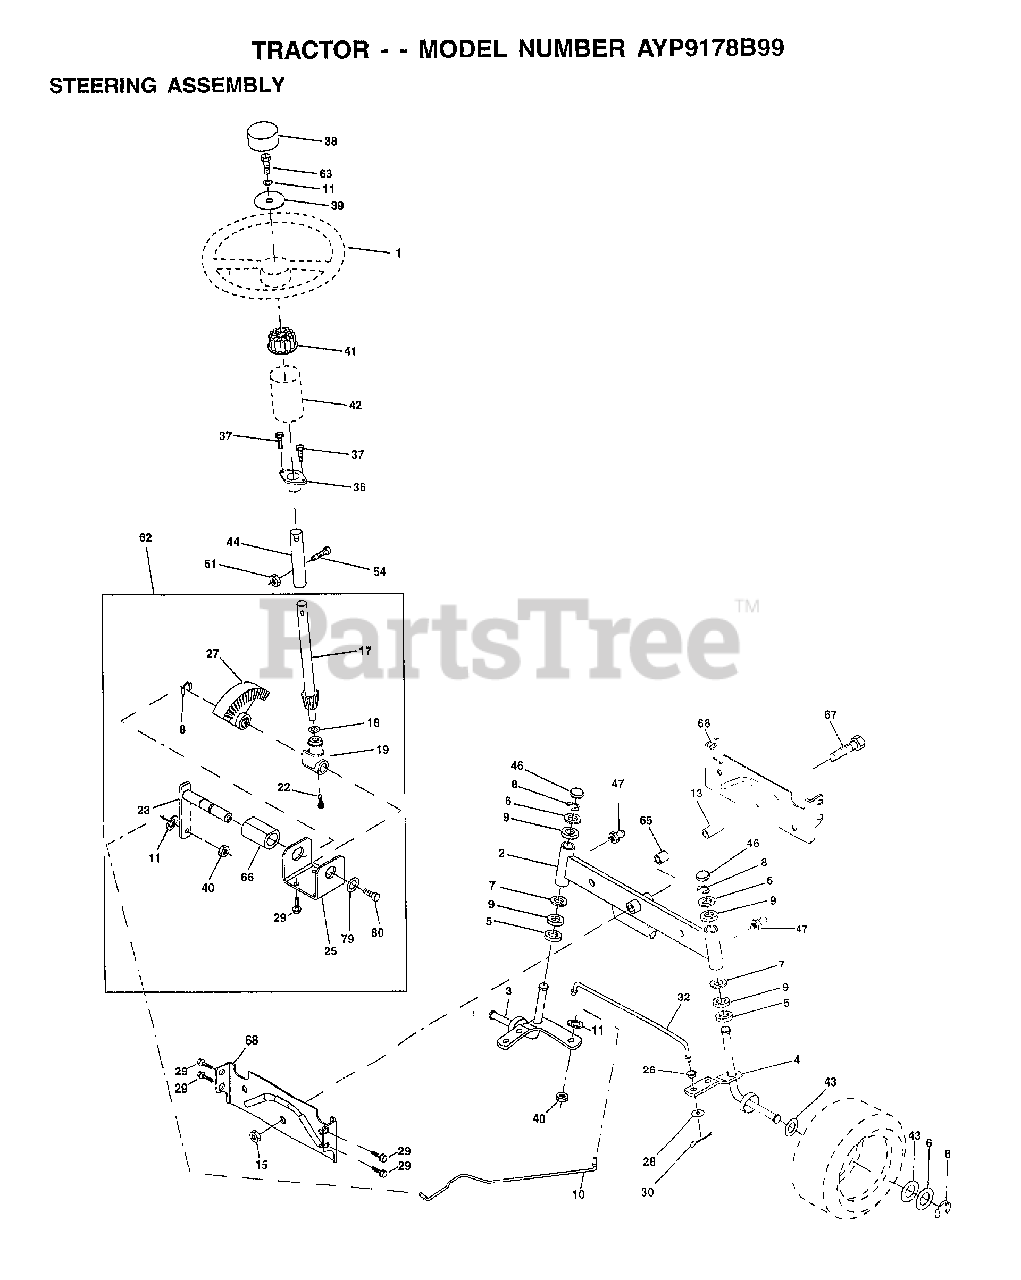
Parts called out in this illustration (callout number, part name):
1	WHEEL STR AYP BLK
2	AXLE ASM
3	SPINDLE.ASM.LH
4	"SPINDLE ASM,RH"
5	WASHER .T
6	WASHER
7	WASHER
8	RING
9	COL. SRTG. BEAR.
10	DRAGLINK-STAMPED
11	LOCKWASHER
13	BEARING AXLE
15	"NUT-LOC,FLANGE LT"
17	SHAFT ASM STEERIN
18	THRUST WASHER
19	SUPPORT.SHAFT.STEER
22	SCREW.HX.WSH.HD
23	SHAFT.ASM.PITMAN
25	BRKT-STEERING
26	BUSHING.DRAGLINK
27	GEAR SECTOR
28	WASHER
29	SCREW
30	COTTER PIN
32	TIE ROD
36	BUSHING.STEERING
37	"SCREW-TT,10-32 FL"
38	CAP STEER AYP
39	WASHER
40	GRIPCO NUT
41	ADAPTER LT
42	BOOT.STEER.PL
43	WASHER
44	EXT SHAFT STEERIN
46	CAP
47	ZERK M
51	NUT
54	BOLT
62	KIT.STEER.ASM
63	BOLT
65	SPACER AXLE
66	"BEARING-ARM,PITMA"
67	BOLT
68	BRACE AXLE
79	WASHER
80	BOLT.HX.NYLON3/8-16X3/
